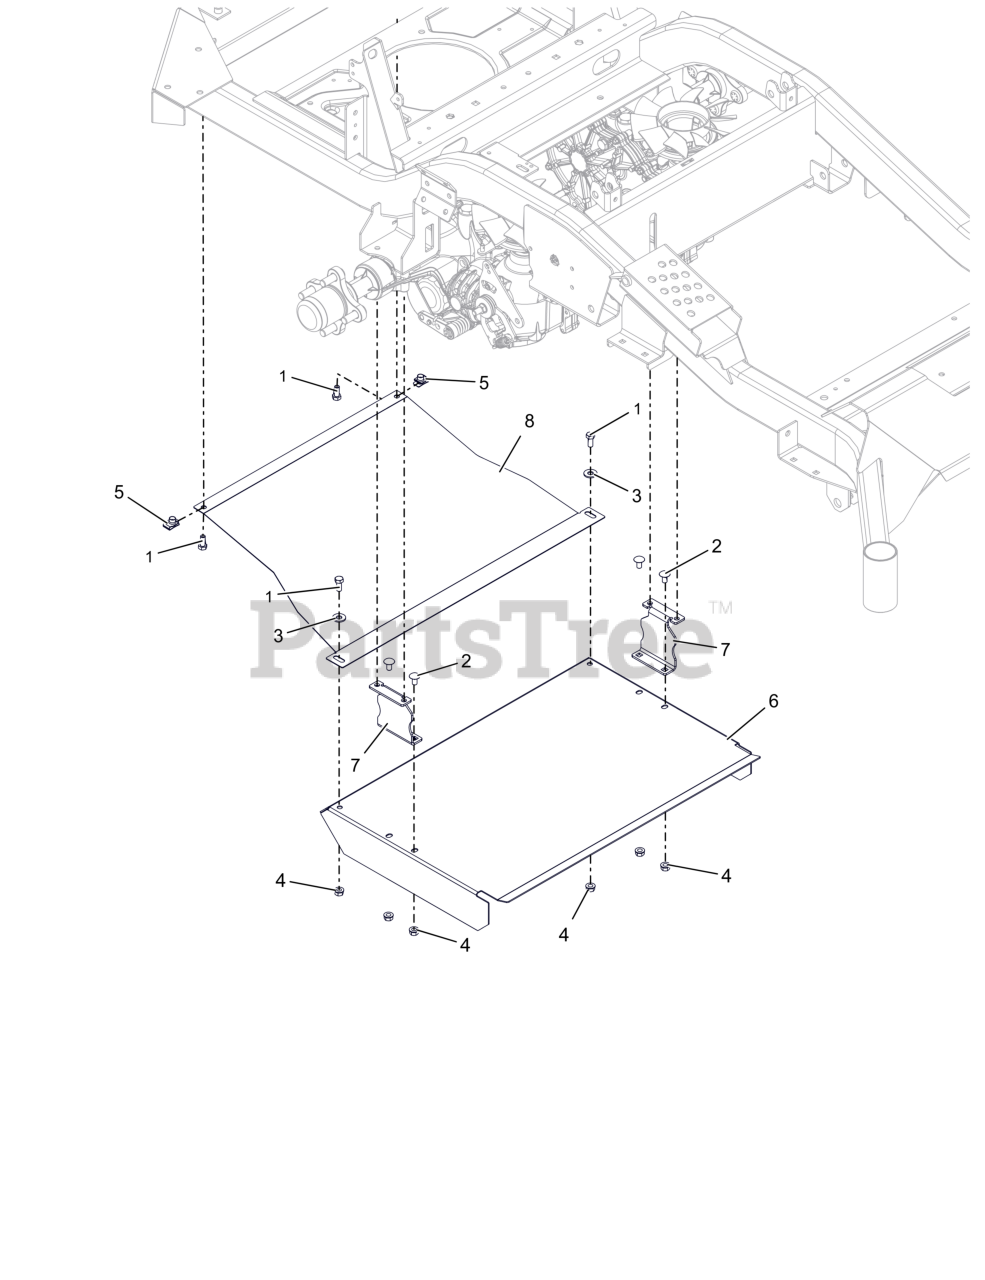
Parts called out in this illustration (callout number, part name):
1	BLT,HEX .31-18X.75 G5 ZCC
2	BLT, RHSSN .31-18X.625 G5 ZCC
3	WSHR,FLT .375X.875X.083 ZCC
4	NUT,LK-CTR-FLG .31-18 GF ZCC
5	NUT-CLIP RETAINER 5/16-18X.56
6	DEFLECTOR- TRANSAXLE
7	BRKT, DEFLECTOR SUPPORT
8	DEFLECTOR, UNDERBODY
